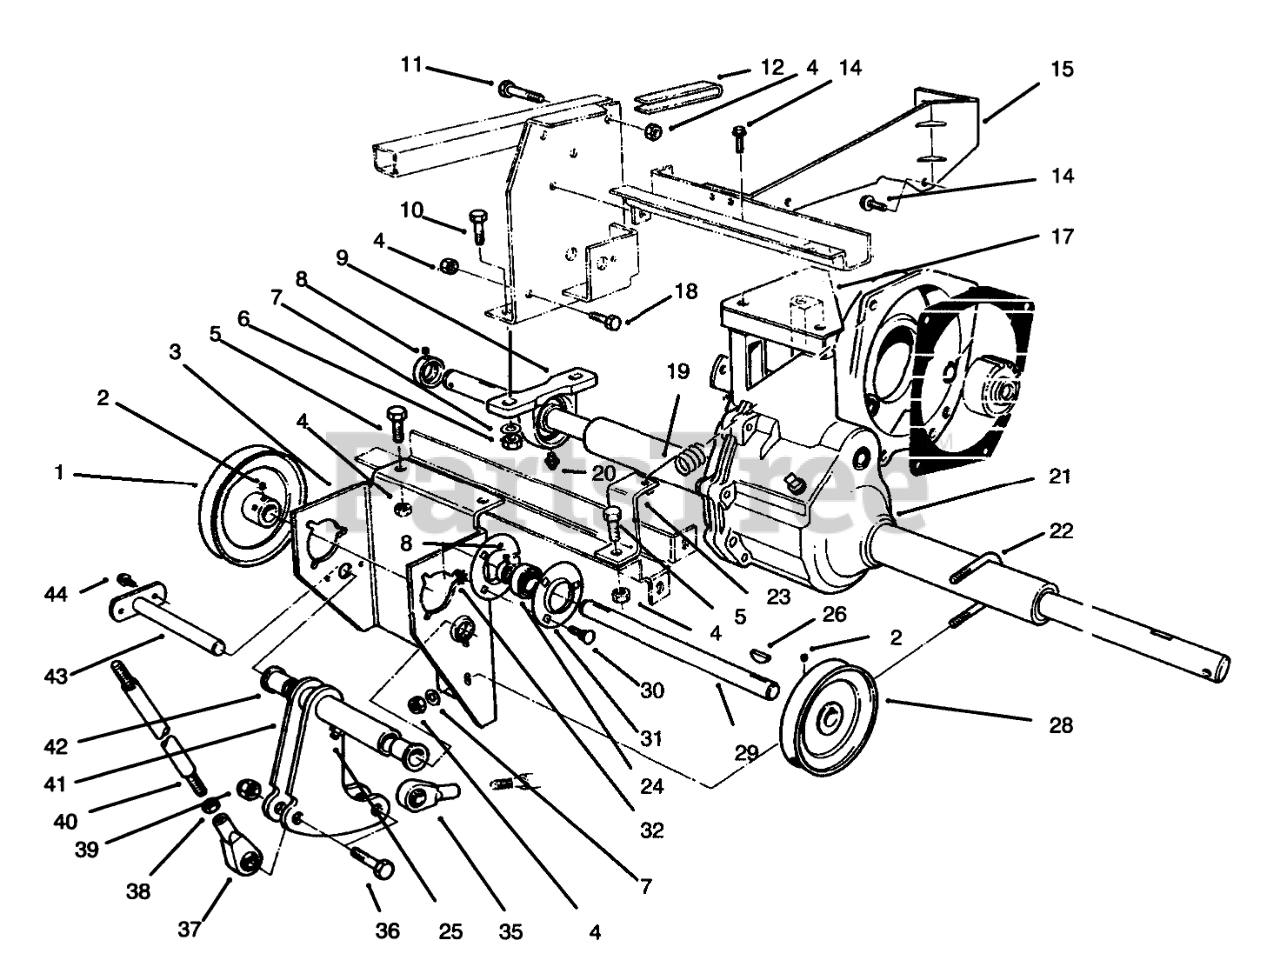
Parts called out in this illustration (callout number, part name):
1	JACKSHAFT OUTPUT PULLEY
2	SCREW-SET, SQH
3	Bracket-Jackshaft
4	NUT-LOCK, NI
5	SCREW-HH
6	NUT-LOCK, NI
7	WASHER-FLAT
8	SCREW-SET, HSH
9	BEARING - PILLOW BLOCK
10	SCREW-HH
11	SCREW-HH
12	TUBE SPACER
14	SCREW-HHF
15	Bracket-Transaxle
17	TRANSAXLE PLATE
18	SCREW-HH
19	SPRING-EXTENSION
20	FITTING-GREASE
21	Differential Assembly
22	U-BOLT
23	Bracket-Spring
24	BEARING-BALL
25	GREASE FITTING
26	KEY-WOODRUFF
28	JACKSHAFT INPUT PULLEY
29	JACKSHAFT
30	BOLT-CARR
31	FLANGE
32	NUT-KEPS
35	BALL JOINT LH
36	SCREW-HH
37	BALL JOINT RH
38	NUT-JAM
39	NUT-LOCK, NI
40	Rod-Steering
41	Bellcrank Assembly (Incl. Ref. #25 & 42)
42	BUSHING PM
43	Shaft-Bellcrank
44	SCREW-HHFTF
